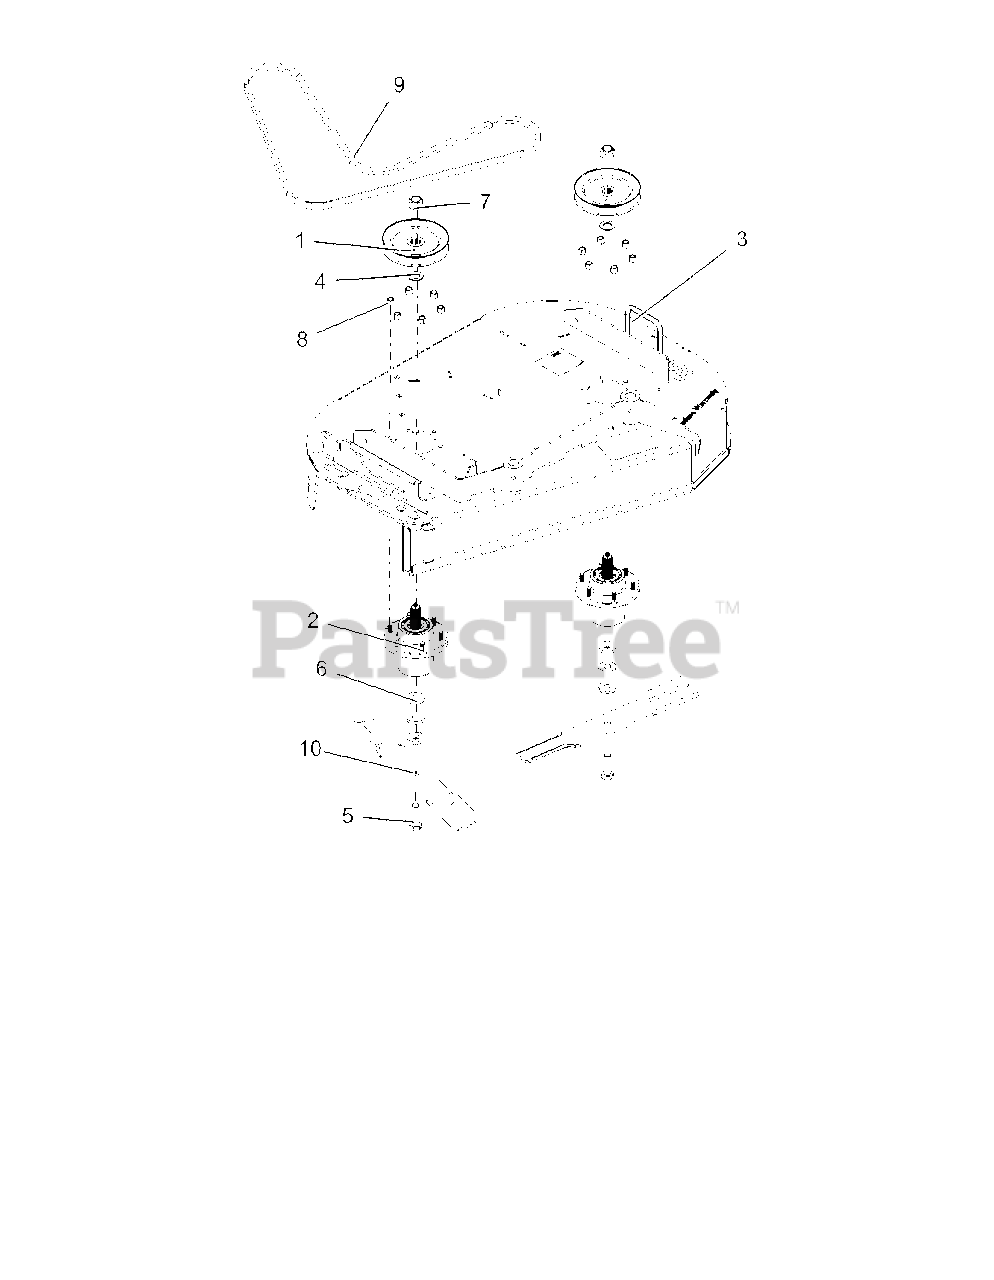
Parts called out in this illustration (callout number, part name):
1	PULLEY, SPINDLE 5.75 X .76-BLACK
2	ASSY, SPINDLE HOUSING
3	ASSY, 36" FLWLK DECK W/DECALS
4	WASHER, .75X1.3125X.120
5	BLT-HEX .62-11X2.00 GR8 YWZC
6	WSHR-FL-STL .630X1.50X.25 YWZC
7	LOCKNUT, 3/4-16 CROWN GR5 Y
8	NUT-LK-NYL .38-16 YWZC
10	BLADE, 18.000 X .80 LIFT
